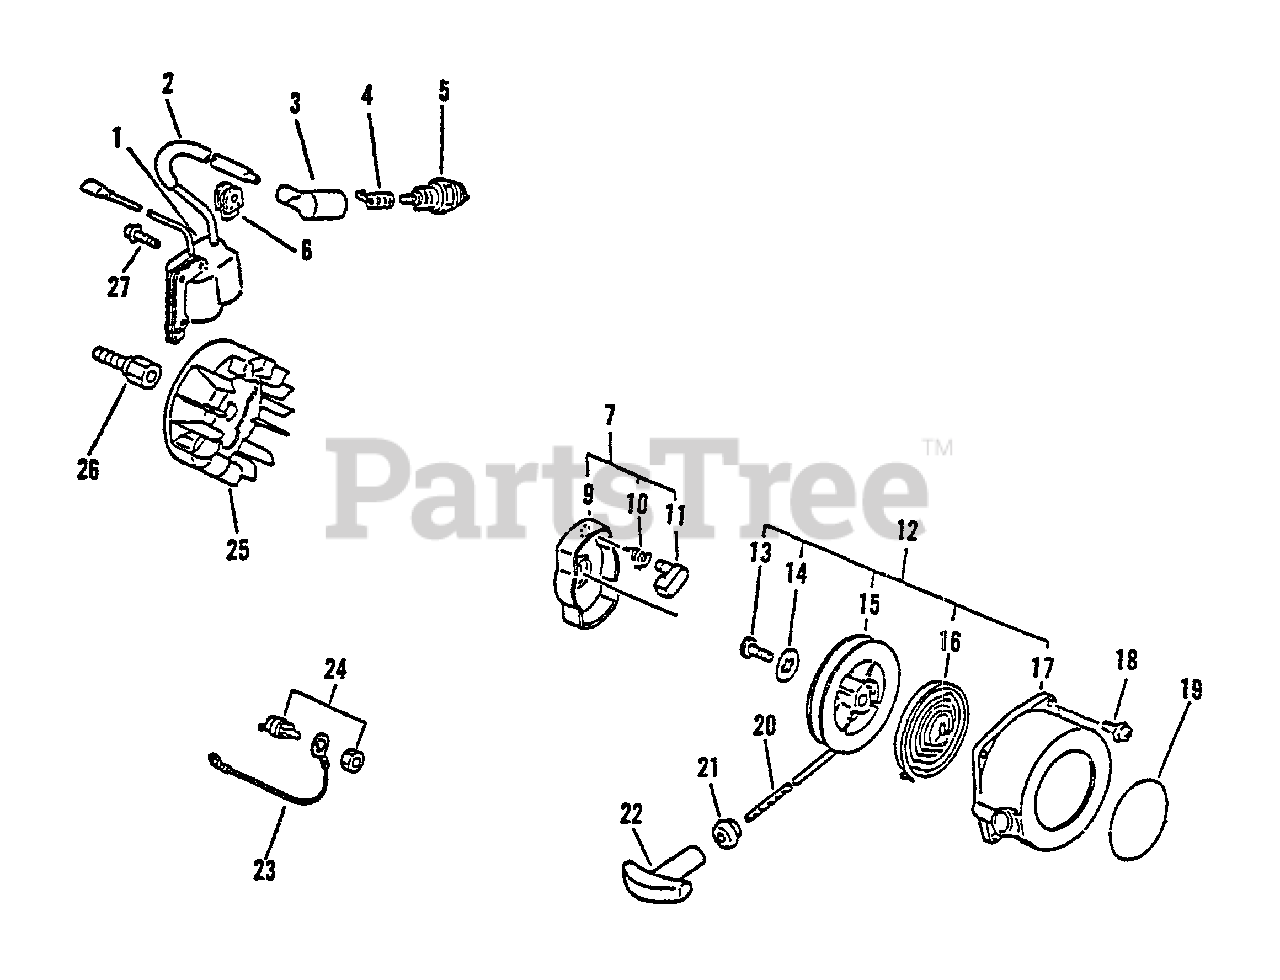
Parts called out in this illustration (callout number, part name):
1	COIL, IGNITION
3	CAP, SPARK PLUG
4	TERMINAL, SPARK PLUG
5	SPARK PLUG - BPM7A
5	SPARK PLUG - BPMR7A
7	PAWL ASSY, STARTER
9	CATCHER, PAWL
10	SPRING, RETURN
11	PAWL, STARTER - BLACK
12	STARTER ASSY
13	SCREW
14	WASHER
15	REEL, ROPE
16	SPRING, RECOIL
17	CASE, RECOIL STARTER
18	SCREW 4×18
19	LABEL, ECHO
21	GUIDE, ROPE
22	GRIP, STARTER
23	LEAD - GROUND
24	SWITCH, ON-OFF
25	FLYWHEEL
26	HUB, FAN
27	SCREW 4×22
